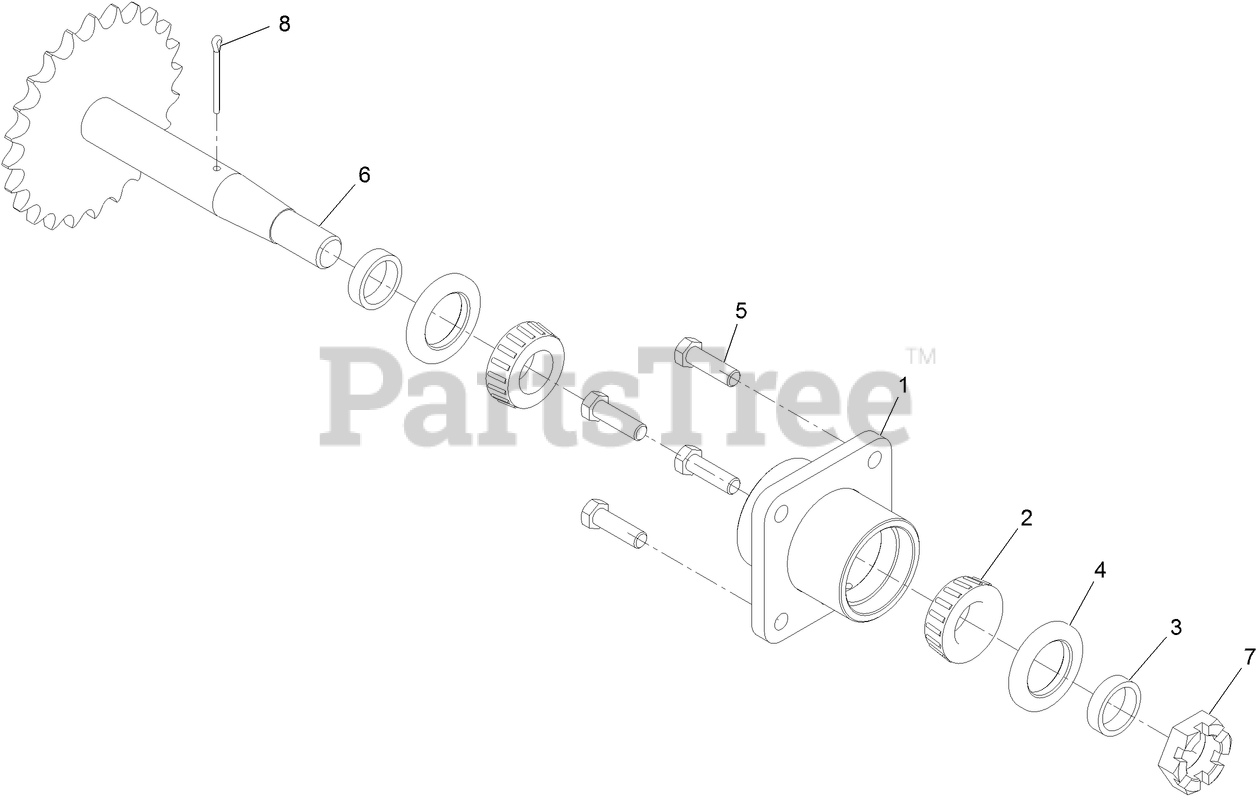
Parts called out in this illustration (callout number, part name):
1	MOUNT-BEARING, WHEEL
2	BEARING-ROLLER, TAPERED
3	SPACER
4	Seal-Grease
5	SCREW-HH
6	AXLE
8	PIN-COTTER
